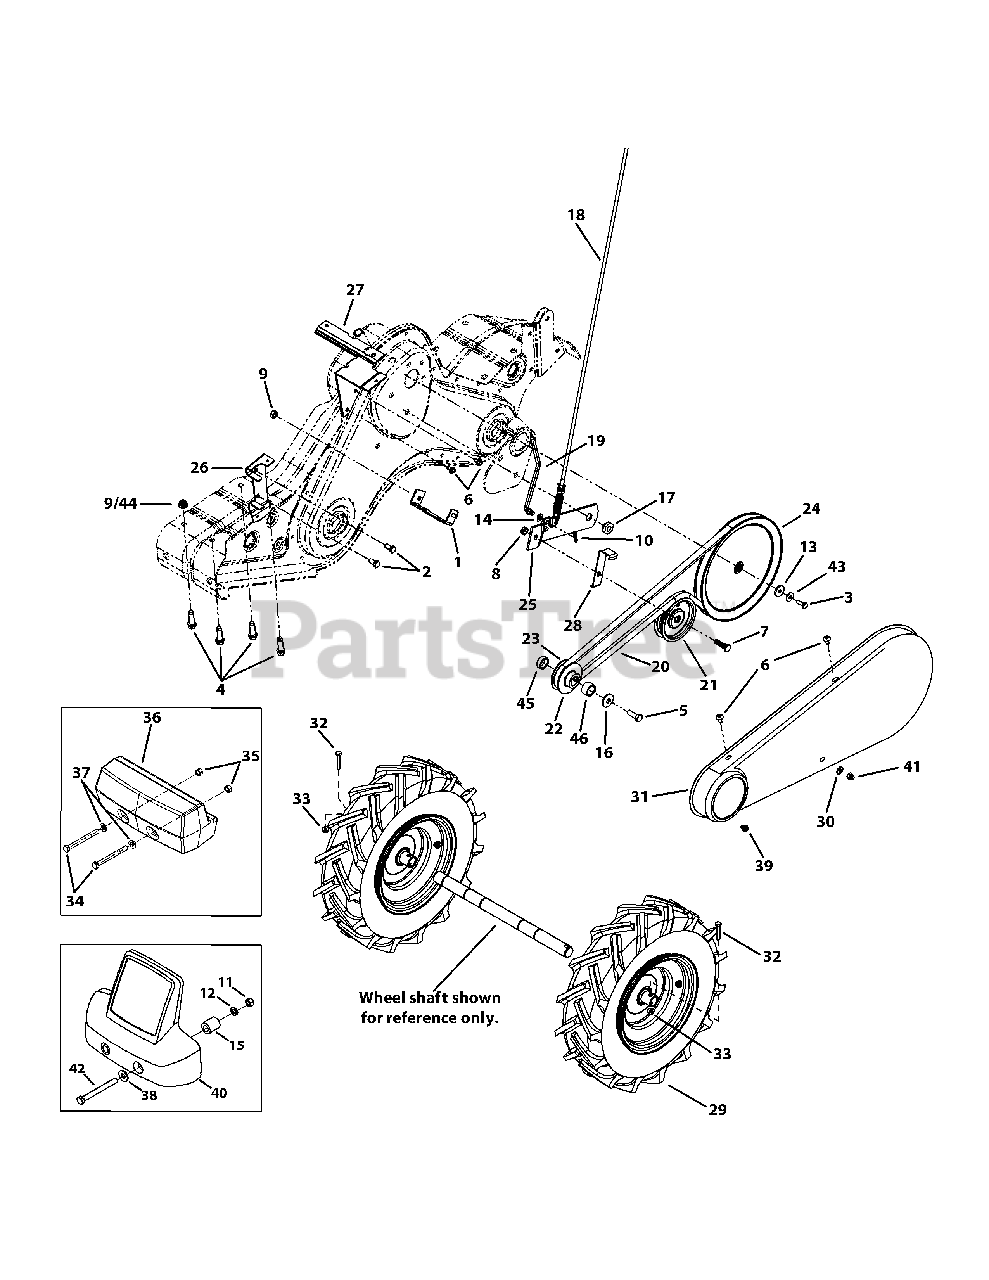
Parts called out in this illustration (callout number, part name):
1	Belt Cover Bracket Assembly
2	Hex Bolt, 5/16-24 x .625
3	Hex Bolt, 1/4-28 x .625"
4	Hex Screw, 3/8-16 x 1.50" (Honda)
5	Hex Bolt, 3/8-24 x 1.0
6	Hex Washer Screw
7	Hex Cap Screw, 3/8-16 x 1.25
8	Lock Jam Nut, 3/8-16
9	Flangelock Nut, 5/16-18
10	Internal Cotter Pin
11	Hex Nut, 1/2-20
12	Washer, Lock, 1/2
13	Flat Washer, .25 ID x .93 OD
14	Spring Washer, .317 ID x .625 OD
15	Hub, .636 ID x 1.00 OD x .94
16	Bell Washer, .396 ID x 1.14 OD
17	Shoulder Nut, 7/16-20
18	Clutch Cable
19	Idler Pulley Rod
21	Flat Idler w/ Flange, 3.75 OD
22	Outer Engine Pulley Half
23	Inner Engine Pulley Half
24	Input Pulley
25	Idler Bracket
26	Belt Keeper Bracket
27	Shift Cover Bracket
28	Idler Belt Keeper
29	Wheel Assembly, 16.0 x 4.6 x 8
30	Flat Washer, .271 ID x .630 OD
32	Hex Head Screw, 1/4-20
33	Flange Lock Nut, 1/4-20
34	Hex Bolt, 1/2-13 x 5.0
35	Flange Lock Nut, 1/2-13
36	Counterweight, 40 lbs.
37	Flat Washer
38	Washer, Flat, 1/2 x 1.25 x .100
39	Hex Screw, 1/4-20 x .375
40	Counterweight
42	Hex Head Screw, 1/2-13 x 5.50
43	Bell Washer, .265 x .750 x .060
44	Flangelock Nut, 3/8-16
45	Spacer, .766 ID x 1.25 OD x .415 (Kohler)
46	Spacer, 19.5 ID x 25.0 OD x 14.5 (Kohler)
